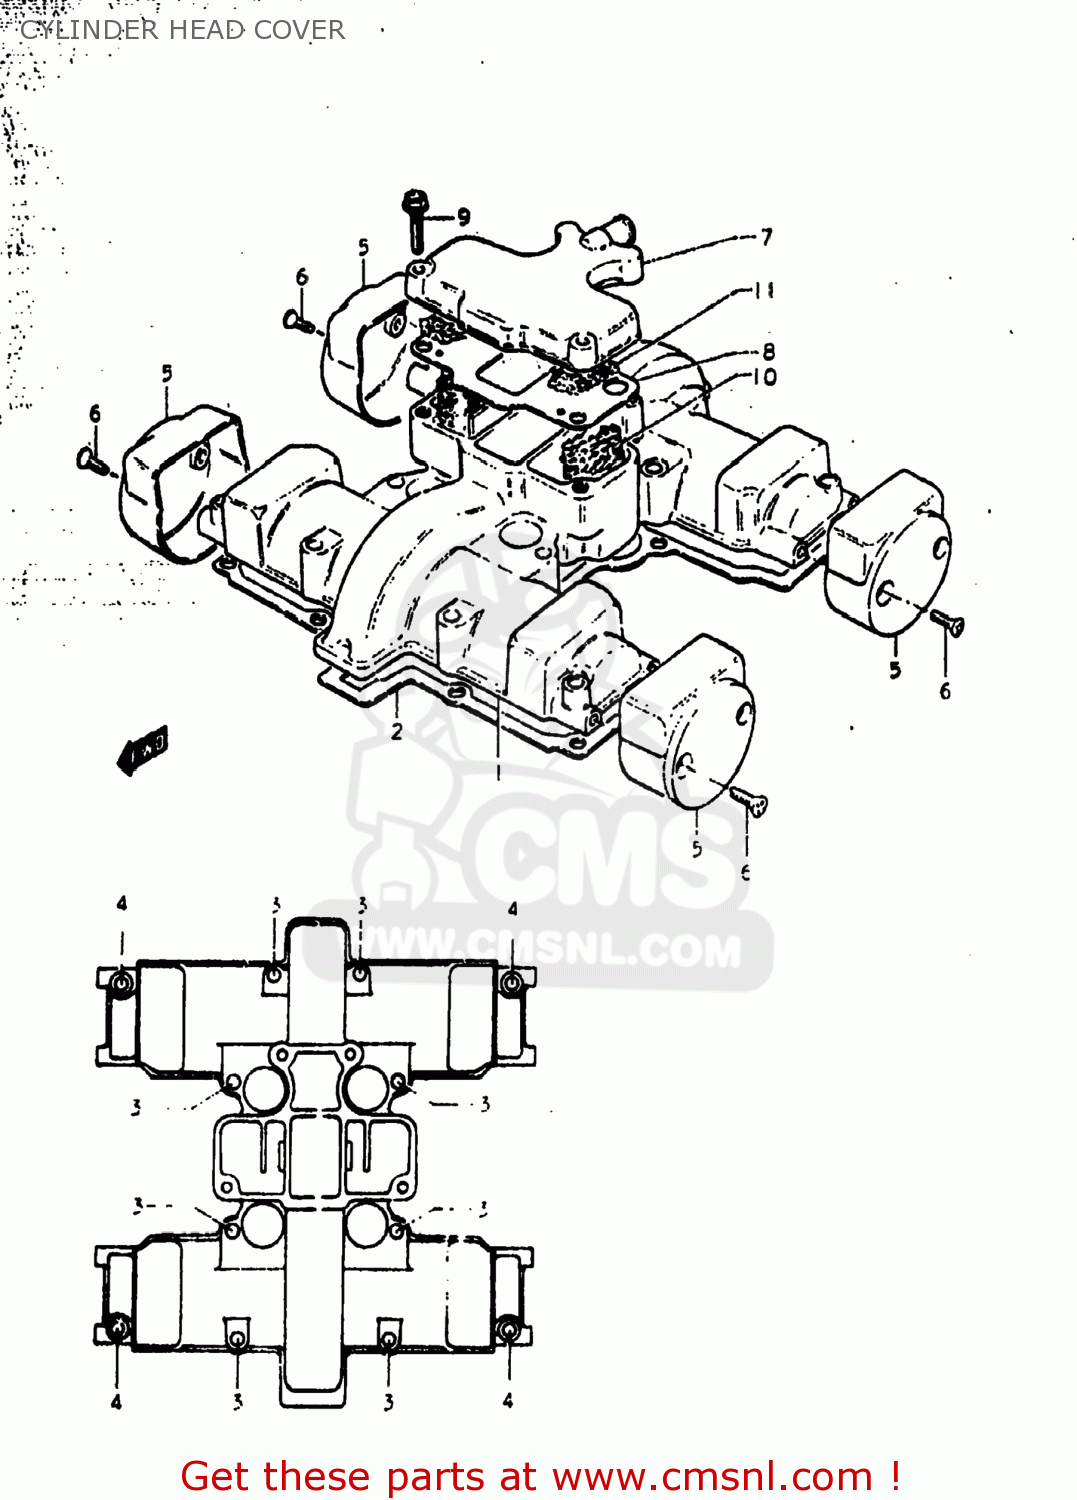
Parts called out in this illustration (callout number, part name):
1	COVER,CYLINDER HEAD
2	GASKET,CYLINDER HEAD COVER (MCA)
3	BOLT
4	BOLT
5	CAP,CYLINDER HEAD COVER
6	SCREW
7	COVER,BREATHER
8	GASKET (MCA)
9	BOLT
10	COVER,BREATHER
11	SEPARATOR,OIL BREATHER
